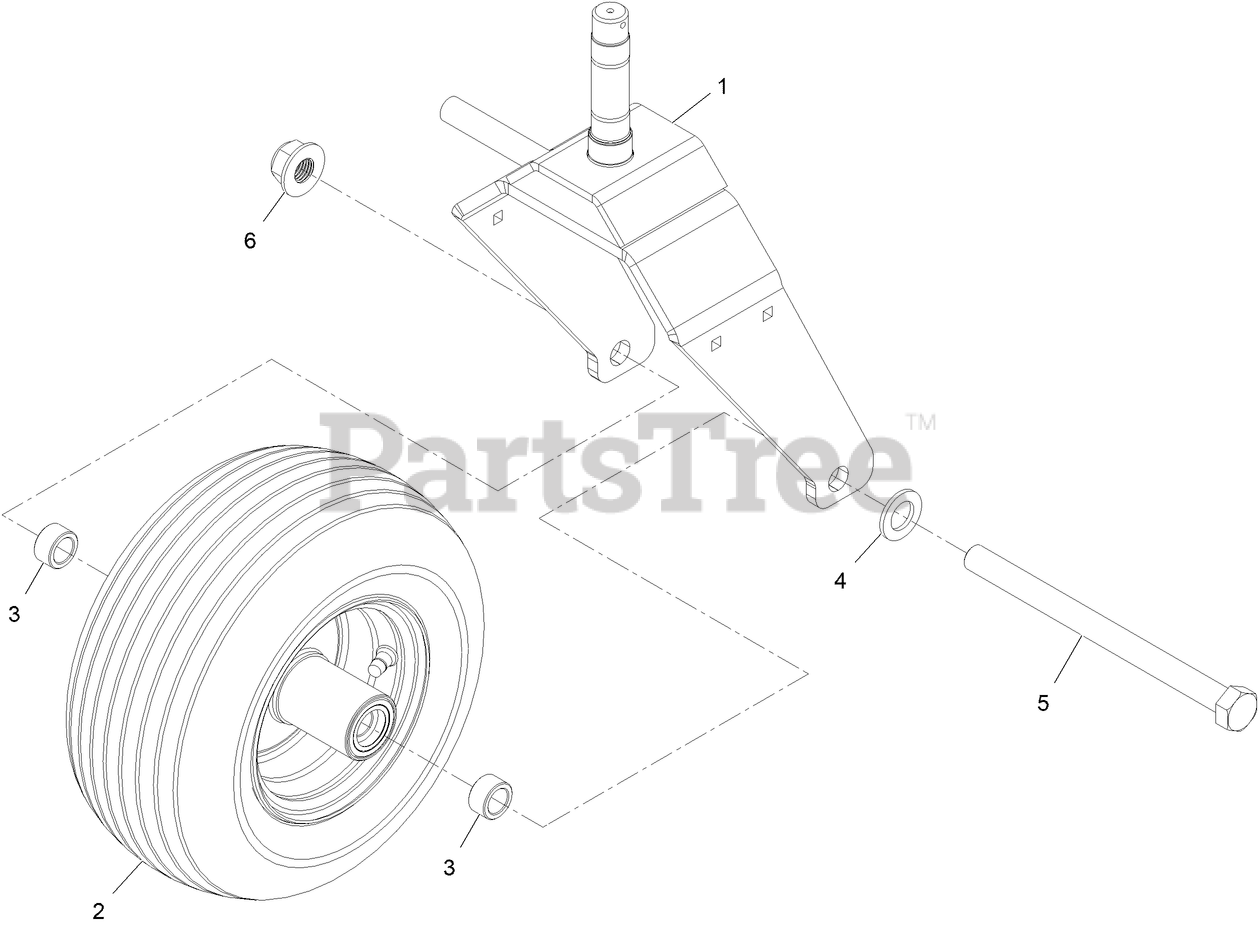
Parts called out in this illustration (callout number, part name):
1	Fork-Caster, LH [red]
2	WHEEL AND TIRE
3	SPACER-AXLE
5	SCREW-HH
